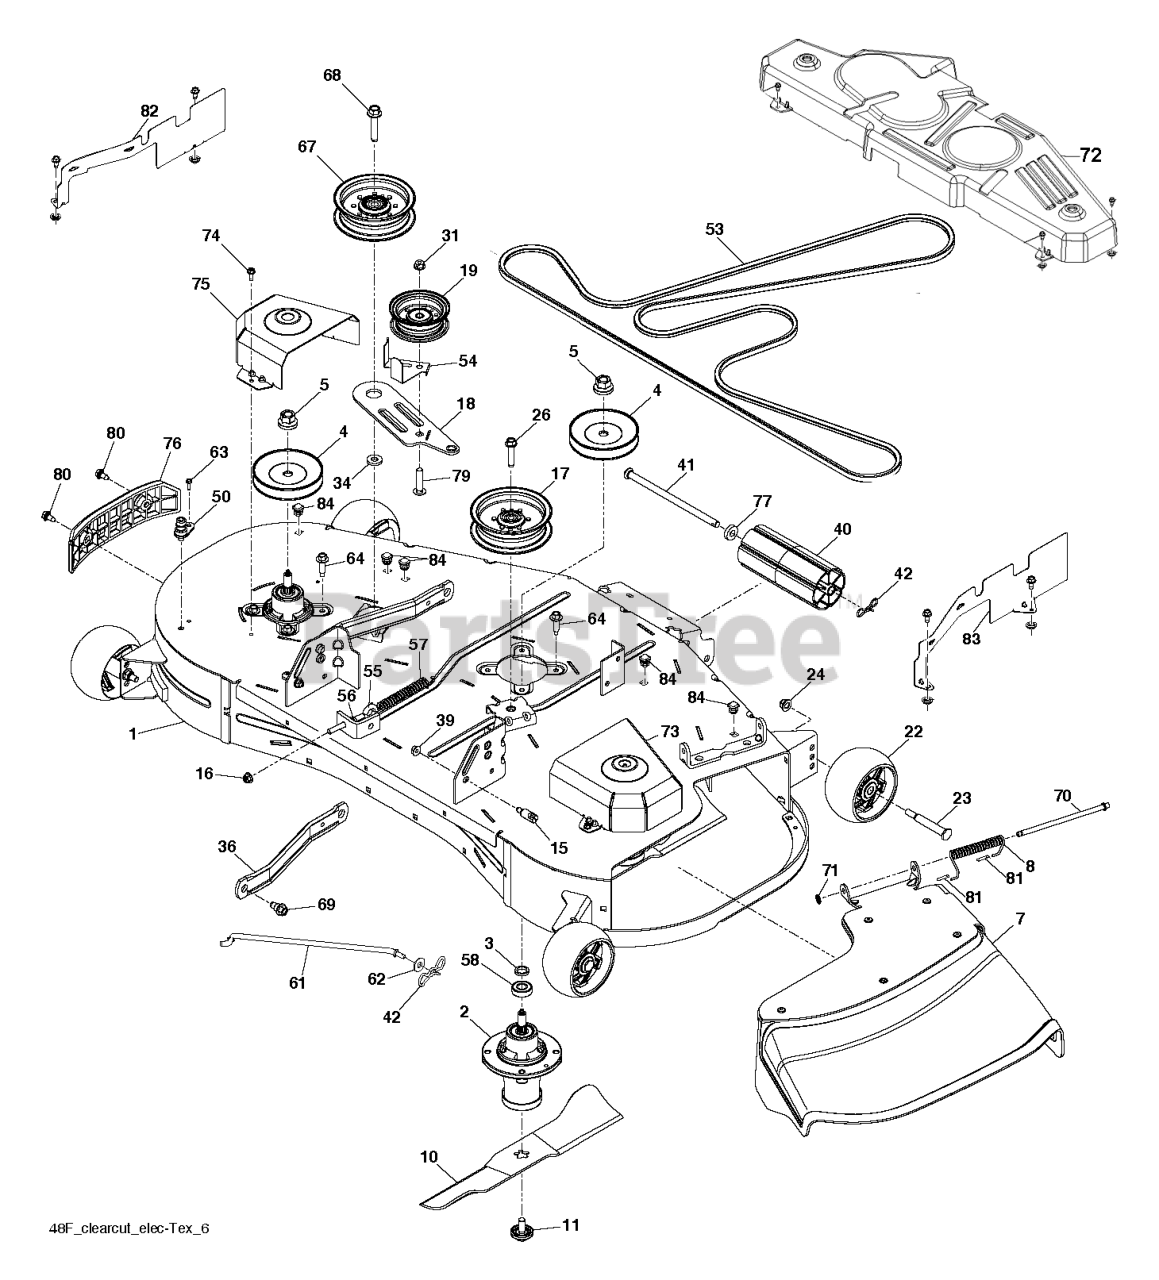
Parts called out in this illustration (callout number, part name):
1	DECK.SVC.48.CC.ASM.668
2	MANDREL ASM, CAST IRON
3	WASHER.SPACER.MANDREL
4	MANDREL PULLEY
7	GSPW Deflectors
8	SPRING.42.FCS.DEFLECTOR
10	BLADE.BAGGER.RES.CLRCT.48".BLK
10	BLADE.48.CC.EURO.RES.BGR.MS431
11	BOLT.WASHER.ASM.7/16-2
15	STUD.W/"D"ANTI-ROTATION
16	NUT HEXAGON FLANGE 5/16-18 ST
17	PULLEY.IDLER.MWR.STATI.LH
18	ARM.PNT.CLUTCHING.EDIP
18	ARM.PNT.CLUTCHING.ASM.EDIP
19	PULLEY.IDLER.48"PRIMARY
22	WHEEL.GAUGE.RALLY
26	SCREW.7/16-14 X 2.125.WASHER
31	NUT LOCK FLG 3/8-16 UNC
36	ARM.RFIXED.MOWER.SUSPNSIONX431
40	NOSE ROLLER 48"
42	PIN.COTTER.5/16.BOW TI
50	PORT.WASHOUT
53	BELT.DECK.TRACTOR
54	GUARD, BELT
55	GSPW Bolts
56	GSPW Hardware
57	SPRING.EXTN.42.FCS.TR.DECK.DRV
61	Rods
61	ROD ROD. SWAY CRD GEN II
62	WASHER
62	Washers
63	Screws
63	PIN.COTTER.5/16.BOW TI
64	BOLT.HEX.WASHR.HED.313-18X1.19
67	PULLEY.IDLER.2006
68	BOLT;HEX_3/8-16 X 1.78.CLRZINC
69	BOLT.SHOULDER
71	NUT PUSH M
72	COVER 48 CLEARCUT EURO TRACTOR
73	COVER.PNT.MANDREL.RH.GREY
74	SCREW.1/4-20X5/8
75	COVER.PNT.MANDREL.LH.TR.GREY
76	BUMPER.ASM.SIDE.TRIM.CLRCUT.48
76	BUMPER 48 CLEARCUT TRIM SIDE A
77	BUSHING.NOSE.ROLLER
80	SHOULDER BOLT 5/16-18TT
81	CAP-SLEEVE LT
82	SHIELD 48 CLEARCUT EURO TRACTO
83	SHIELD 48 CLEARCUT EURO TRACTO
